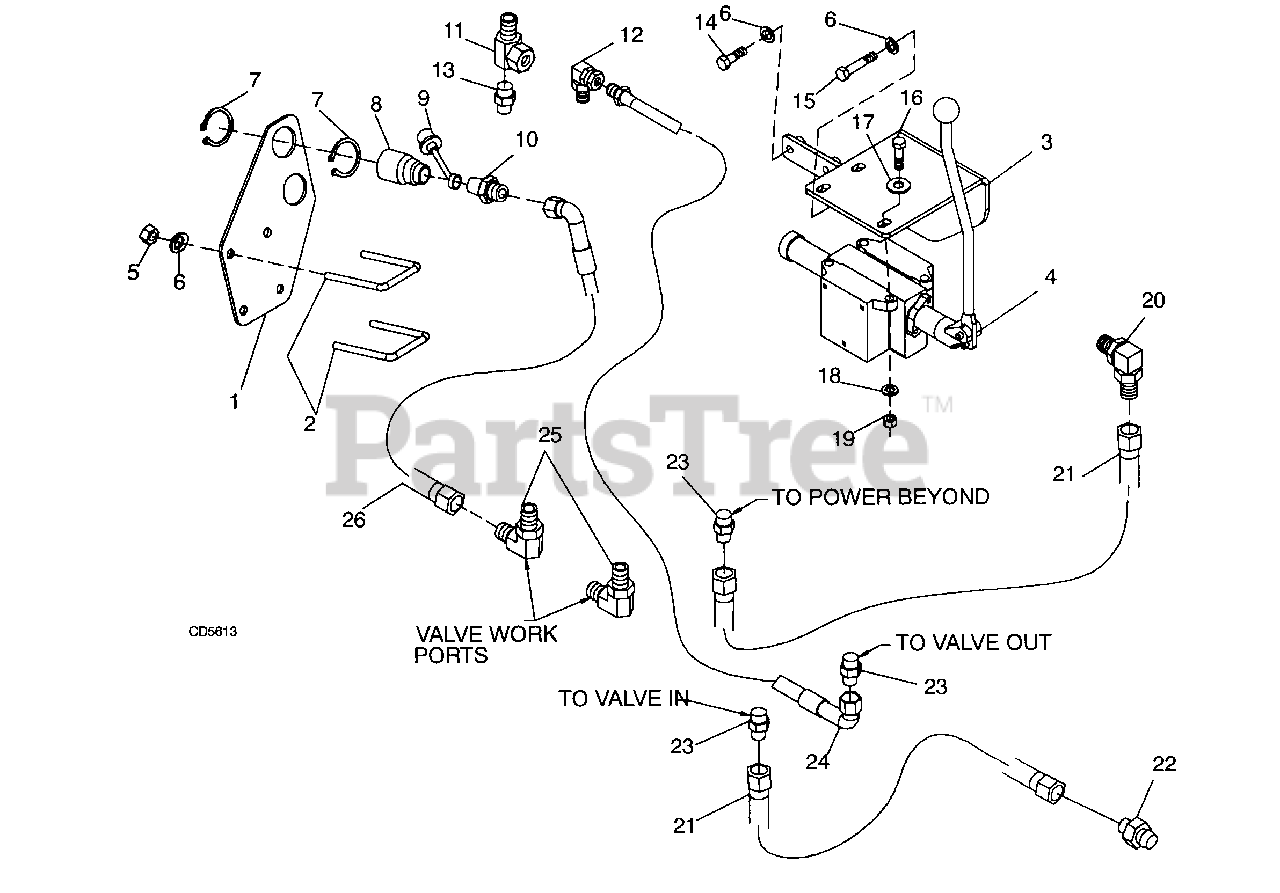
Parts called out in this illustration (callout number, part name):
1	Quick coupler bracket
2	5/16 NC x 2.5 x 4.0 U bolt
3	Valve bracket
4	Single spool control valve with handle
5	5/16 NC Hex nut
6	5/16 Lockwasher, zinc plated
7	1-1/2 Snap ring
8	Quick-attach coupler
9	Dust plug
10	Straight adapter
11	3/8 NPT Tee
12	1/2 male x 3/8 female swivel elbow
13	3/8 NPT x 1/2 NPT Nipple
14	M8-1.25 x 40mm Hex head cap screw, zinc plated
15	M8-1.25 x 70mm Hex head cap screw, zinc plated
16	3/8 NC x 1-1/4 Hex head cap screw, zinc plated
17	3/8 Standard SAE flat washer
18	3/8 Lockwasher, zinc plated
19	3/8 NC Hex nut, plated
20	1/2 BSPPM x 3/4 JICM 90-degree elbow
21	3/8 x 21" x 3/4JICF Hose
22	1/2 BSPPM x 3/4 JICM Adapter
23	Work port fitting
24	3/8 x 30" x 3/8 NPTM x 3/4 JICF 90-degree hose
25	90-degree adjustable elbow
26	3/8 x 32" x 9/16 JICF x 3/4 JICF 90-degree hose
